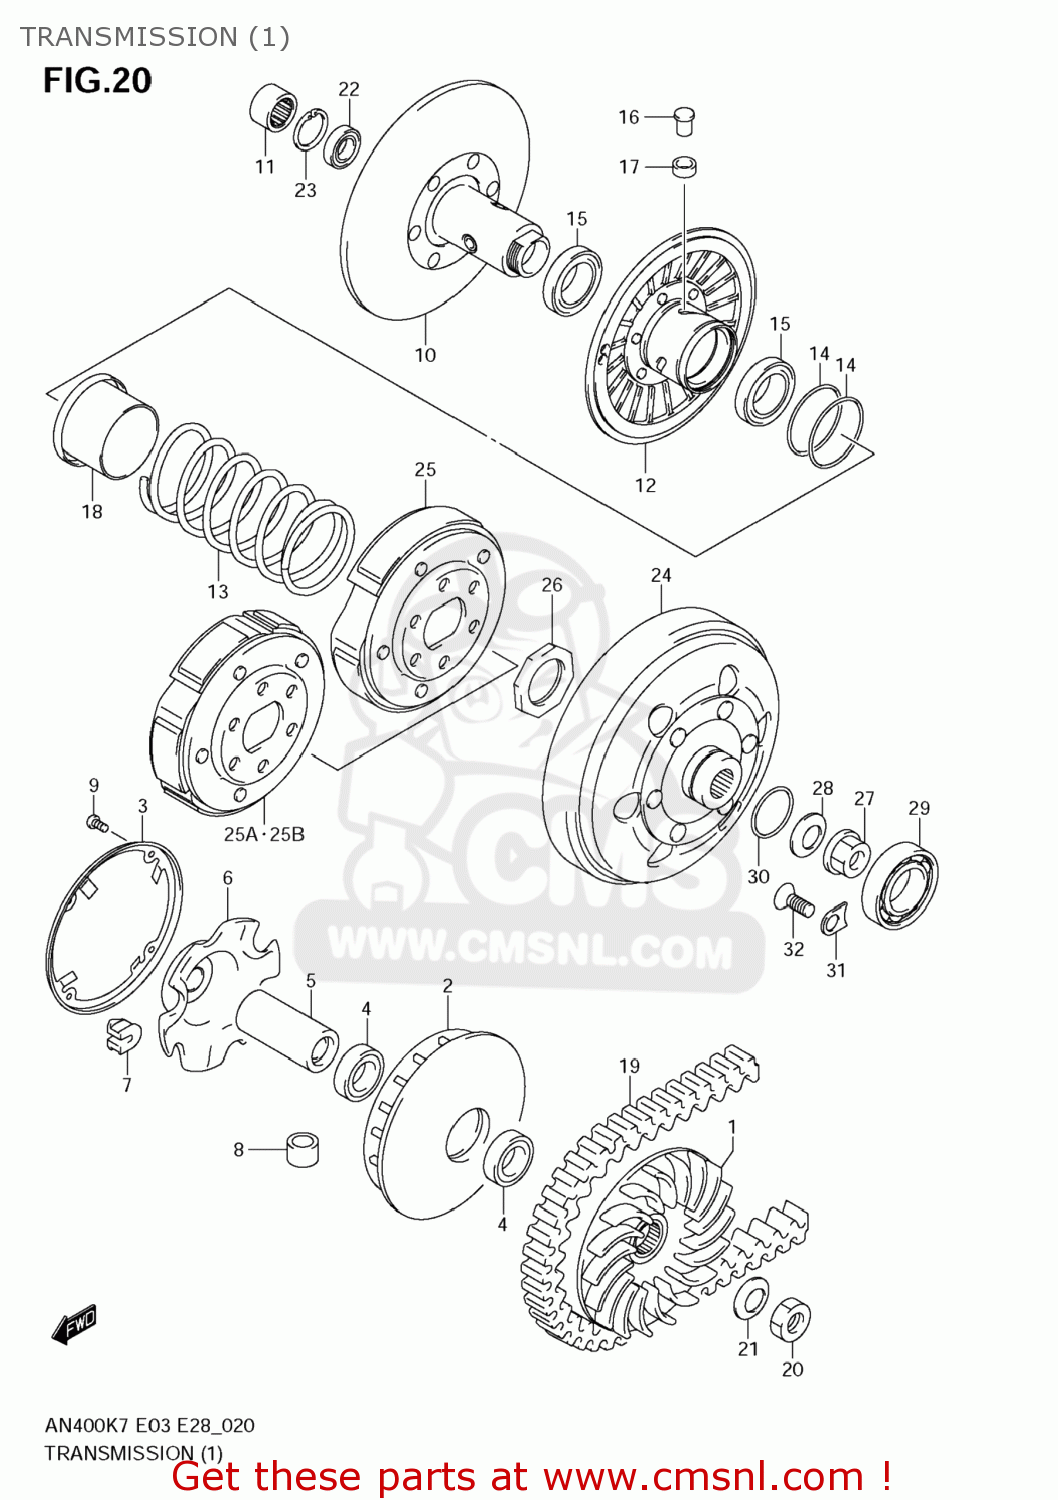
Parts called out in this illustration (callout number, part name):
1	FACE,FIXED DRIVE
2	FACE,MOVABLE DRIVE
3	COVER,MOVABLE DRIVE
4	SEAL,MOVABLE DRIVE FACE OIL
5	SPACER,MOVABLE DRIVE
6	PLATE,MOVABLE DRIVE
7	DAMPER,MOVABLE DRIVE PLATE
8	ROLLER,MOVABLE DRIVEN
9	SCREW
10	FACE,FIXED DRIVEN
11	BEARING,FIXED DRIVEN,R
12	FACE,MOVABLE DRIVEN
13	SPRING,MOVABLE DRIVEN
14	O RING,MOVABLE DRIVEN
15	SEAL,MOVABLE DRIVEN
16	PIN,MOVABLE DRIVEN
17	SPACER,MOVABLE DRIVEN PIN
18	SHEET,MOVABLE DRIVEN
19	V BELT,DRIVE
20	NUT
21	WASHER
22	BEARING
23	CIRCLIP
24	HOUSING, CLUTC
25	CLUTCH ASSY,SHOE (NAS)
25A	CLUTCH ASSY,SH
25B	CLUTCH ASSY,SHOE (NAS)
26	NUT,SHOE CLUTCH
27	NUT
28	WASHER
29	BEARING(35X62X14)
30	O RING(D:2,ID:31)
31	RETAINER
32	SCREW
